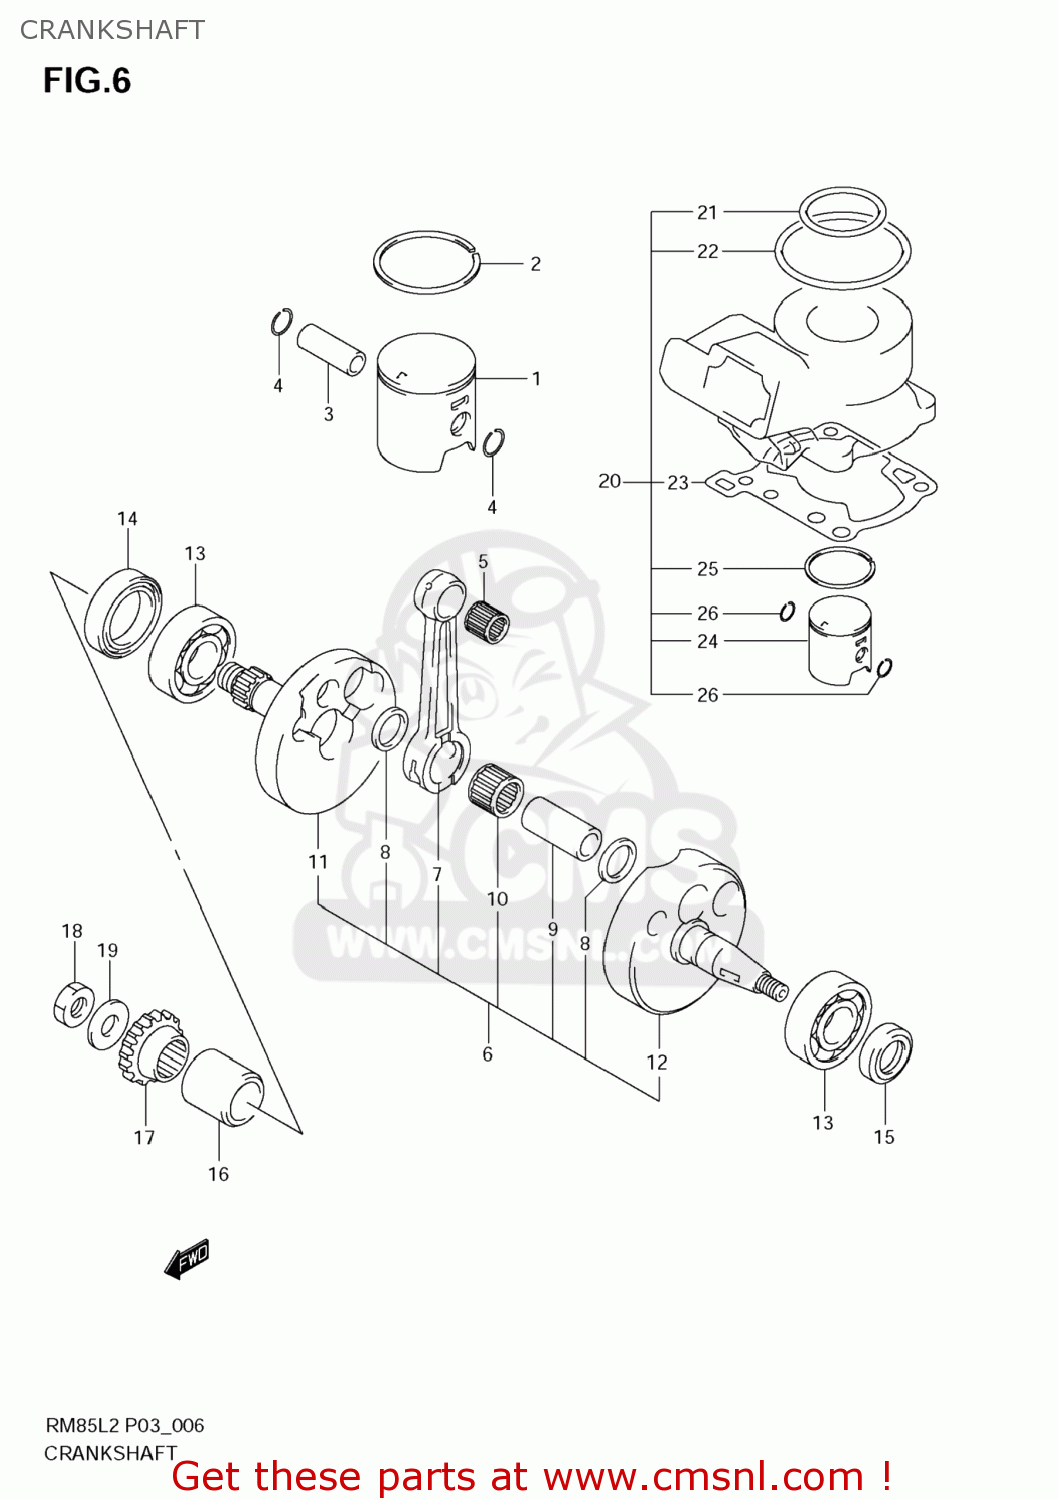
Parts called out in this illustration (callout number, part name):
1	PISTON
2	RING,PISTON
3	PIN,PISTON
4	RING,SNAP 14MM
5	BEARING(14X18X16)
6	CRANKSHAFT ASSY
7	CONNECTING ROD
8	WASHER(20X34X1.5)
9	PIN,CRANK
10	BEARING(20X26X14)
11	CRANKSHAFT,R
12	CRANKSHAFT,L
13	BEARING(20X52X15)
14	SEAL,OIL(30X40X7)
15	SEAL,OIL(18X30X7)
16	SPACER,PRIMARY DRIVE GEAR
17	GEAR,PRIMARY DRIVE(NT:18)
18	NUT
19	WASHER
20	TOP END KIT,ENGINE
21	O RING,CYLINDER HEAD NO.1
22	O RING,CYLINDER HEAD NO.2
23	GASKET,CYLINDER (NAS)
24	PISTON
25	RING,PISTON
26	RING,SNAP 14MM
